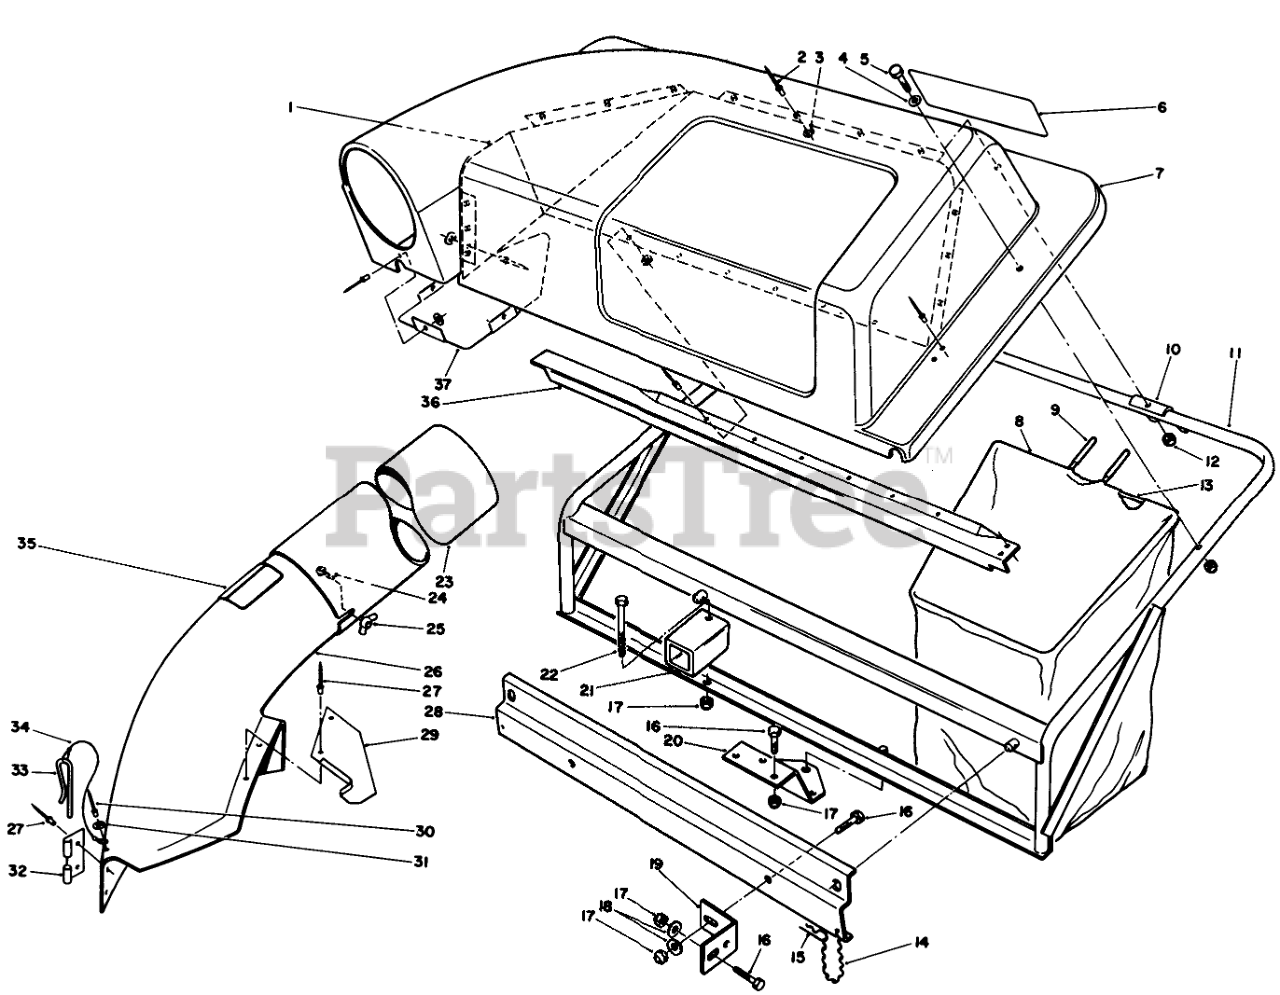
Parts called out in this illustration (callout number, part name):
1	Screen Cover
2	RIVET-POP
3	WASHER-FLAT
4	WASHER-PLAIN
5	SCREW-HH
6	TWIN BAGGER DECAL
7	Cover
9	GRIP-HANDLE, BAG
10	BAG FRAME BRKT
11	Frame
12	NUT-LOCK, CAP
13	Frame-Bag
14	6-LINK CHAIN W/HOOK
15	PIN-HAIR
16	SCREW-HH
17	NUT-LOCK, NI
18	WASHER-PLAIN
19	MTG BRACKET
20	MTG PLATE B
21	FRAME SUPT TUBE B
22	SCREW-HH
23	TUBE(ROUND&LONG)
24	BOLT-CARR
25	NUT-WING SPECL
26	Chute Assembly (Incl. Ref. #27, 29-35)
27	RIVET-BLIND
28	Bracket Frame Support
29	CHUTE SUPT BRKT
30	RIVET-BLIND
31	WASHER-PLAIN
32	BRACKET-MOUNTING, CHUTE
33	PIN-LOCKING, CHUTE
34	LANYARD
35	DECAL-DANGER
36	SCREEN SUPT BRKT B
37	Shield Cover
